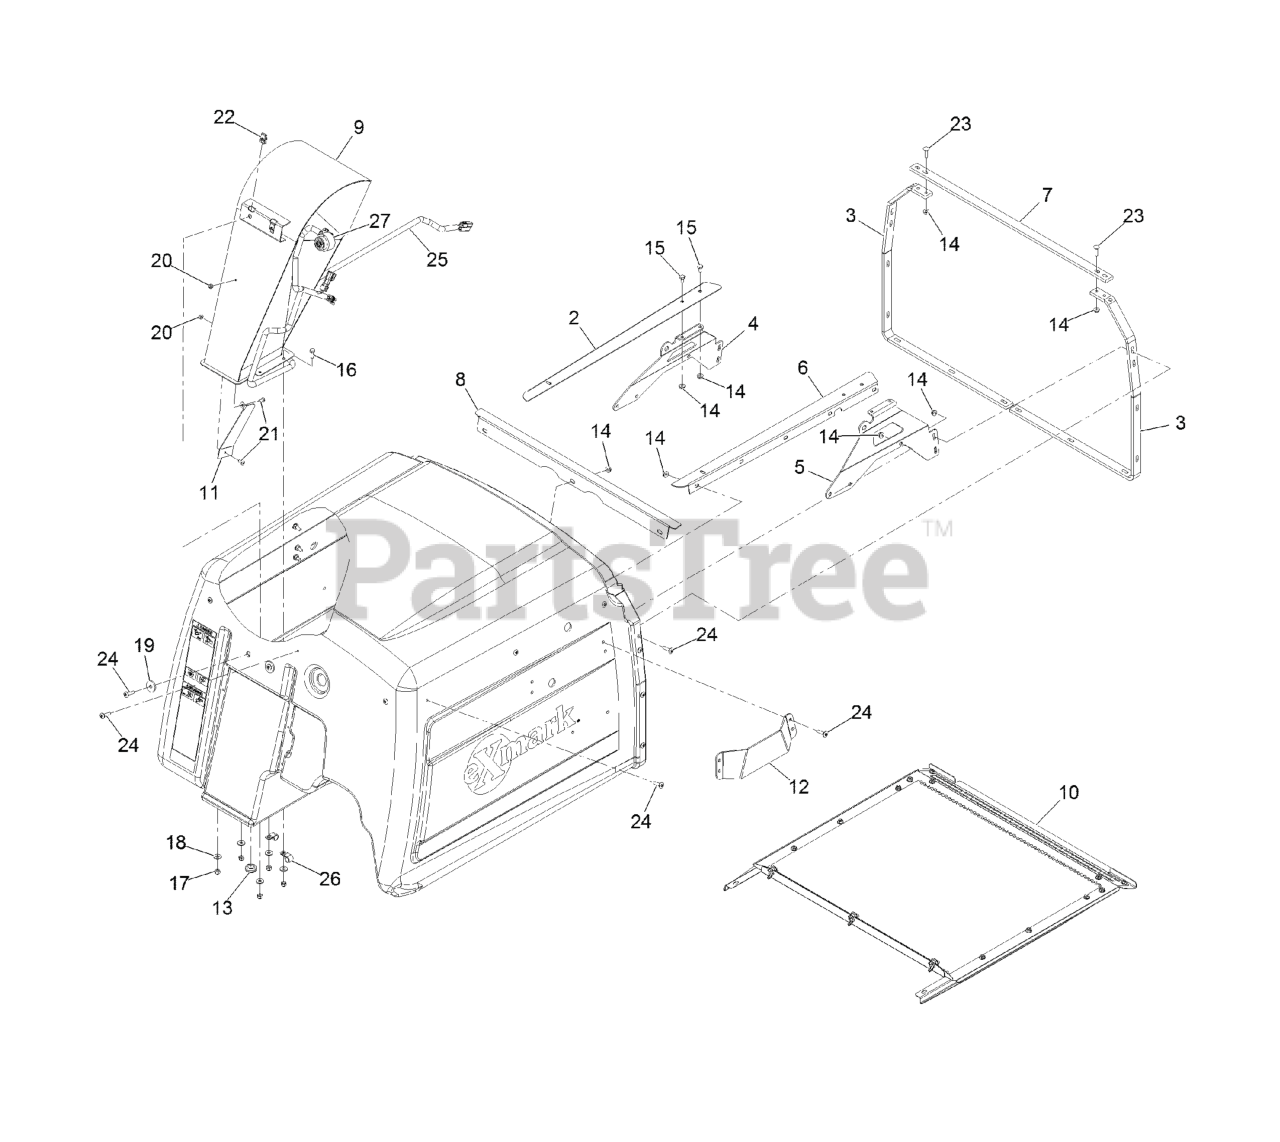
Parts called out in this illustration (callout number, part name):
2	ANGLE-SCREEN TRACK, RH
3	REINFORCEMENT-HOPPER
4	BRACE-DOOR PIVOT, RH
5	BRACE-DOOR PIVOT, LH
6	ANGLE-SCREEN TRACK, LH
7	BRACKET-FRAME CONNECT
8	CHANNEL-SCREEN, FRONT
10	HOPPER SCREEN ASM
11	DEFLECTOR-DISCHARGE CHUTE
12	PLATE-GUARD
13	GROMMET
15	SCREW-HH
16	SCREW-HH
17	NUT-LOCK, NI
18	WASHER-FLAT
20	NUT-LOCK, NI
21	SCREW-PTH
23	SCREW-CARR
24	SCREW-TTH
25	HARNESS-WIRE, HOPPER
26	CLIP-LOOM
27	ALARM-TONE, DUAL
